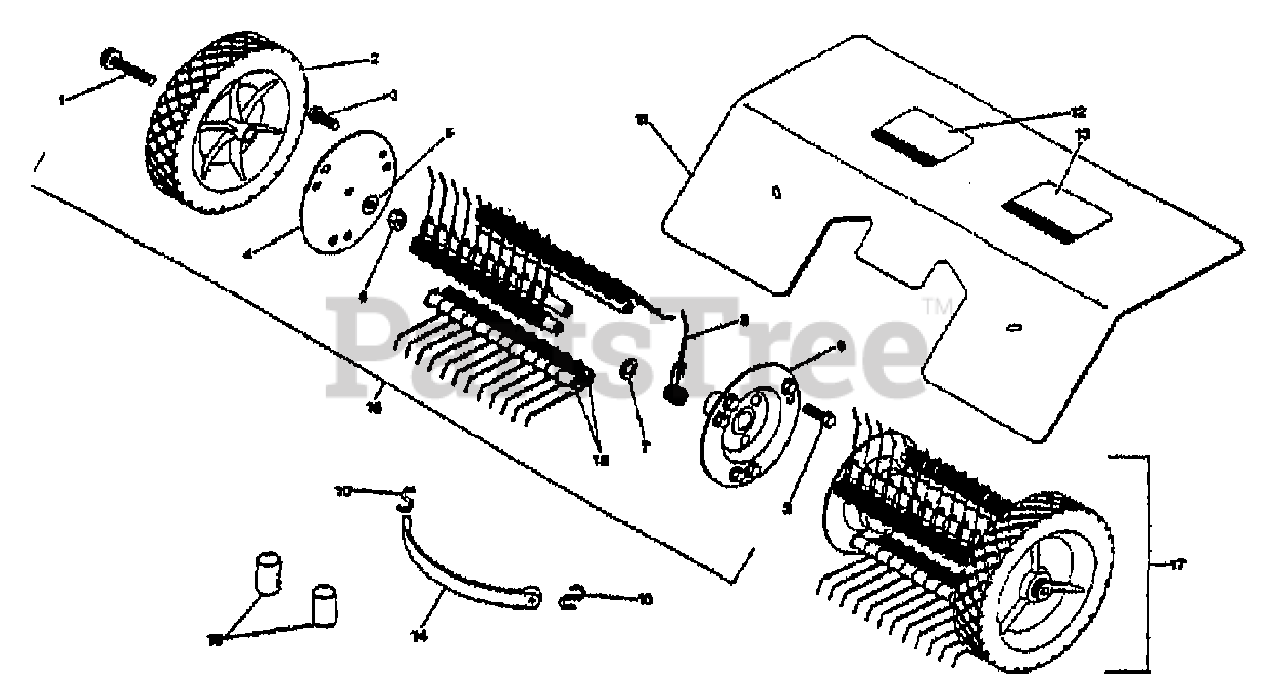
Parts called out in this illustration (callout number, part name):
1	BOLT-SC HD 1/2X1 1/2
2	ASSM-WHEEL & TIRE
3	SCR-WHIZ 5/16-18X3/4 LK
4	END CAP-OUTER
5	WASHER-LK .375 @ DEPL
6	NUT-HEX 3/8-16 ZP
7	WASHER-FL 1/2 ID-7/8 OD
8	KIT-SPRING TINE (12 SPRING)
8	KIT-SPRING TINE (36 SPRING)
9	END CAP-INNER
10	S-HOOK (DEBRIS SHIELD)
11	ASSM-HOOD W/DECALS
12	DECAL-CAUTION
13	DECAL-WARNING
14	STRAP-DEBRIS SHIELD
15	BAR-SPRING TINE RETAIN
16	ASSM-DETHATCHER RT
17	ASSM-DETHATCHER LT
18	SPACER-TINE 1.0X.8X1.31LG
